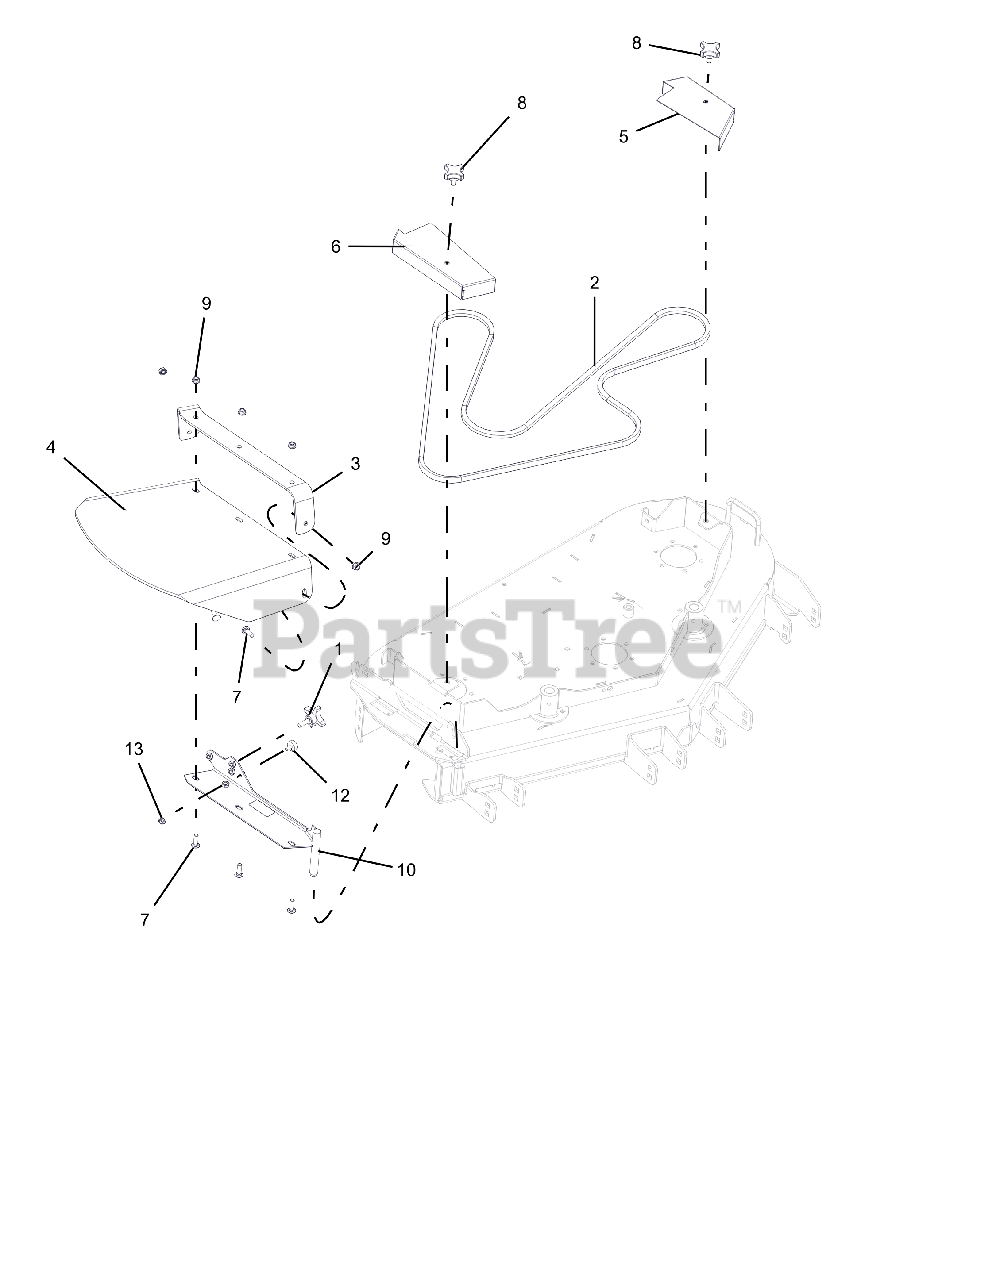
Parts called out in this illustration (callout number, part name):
1	KNOB, 3/8 X 1.25 - 4 PRONG
2	BELT, HB
3	STRAP, WALK RUBBER DISCHARGE-RED
4	SHIELD, WALK RUBBER DISCHARGE
5	SHIELD, LH SPINDLE 48 FLWLK-RED
6	SHIELD, RH SPINDLE 48 FLWLK G2-RED
7	BLT-RDHDSQNK .38-16X1.25 G5 YWZC
8	KNOB, 3/8-16 x .75
9	@NUT-SPNLK-FLG .375-16 YWZC
10	WLDT. DISCHARGE-RED
12	BUMPER, RUBBER
13	@NUT-SPNLK-FLG .312-18 YWZC
